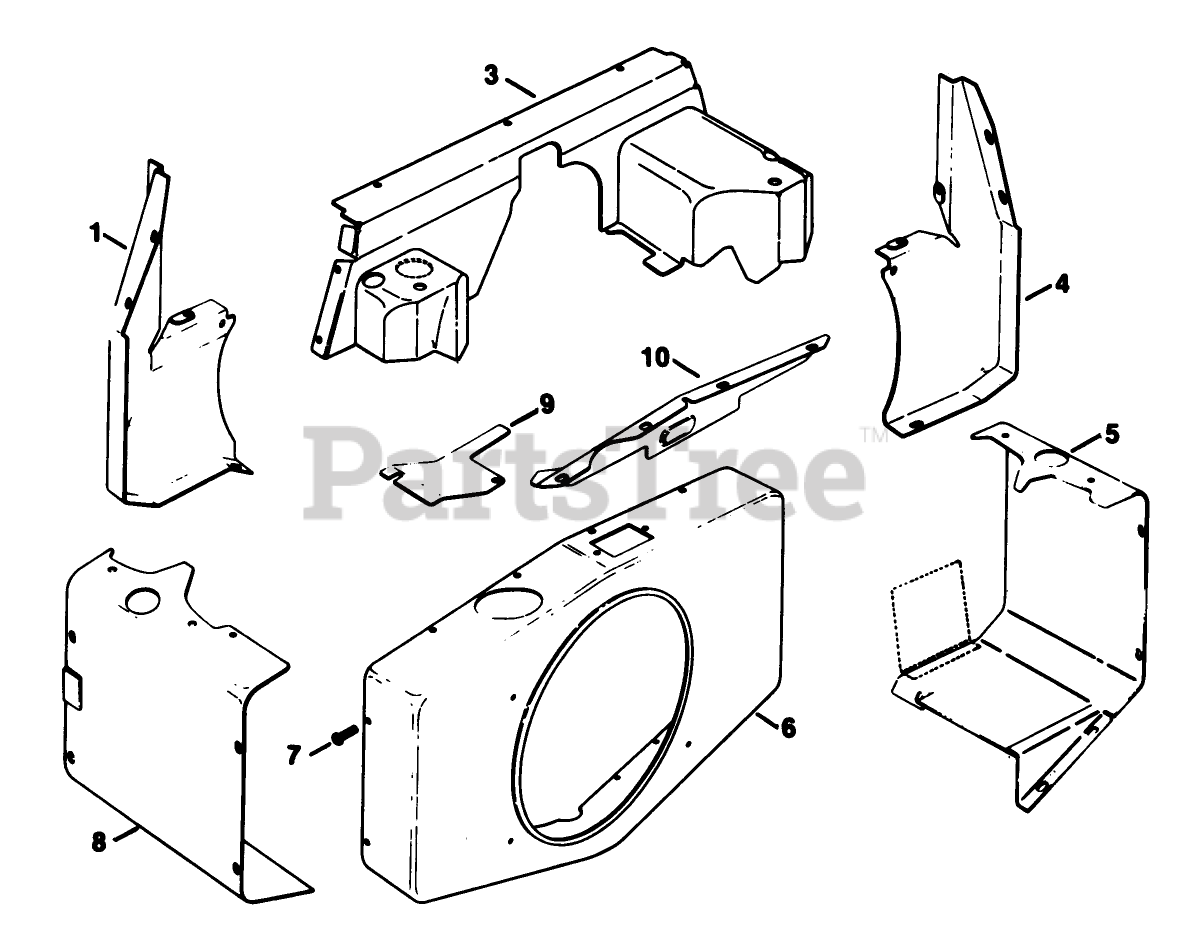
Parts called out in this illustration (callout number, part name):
1	Duct-#2 Side Air
3	Cover-Air Duct
4	#1 Side-Air Duct
5	Baffle-#1 Cylinder Head
6	Housing Blower
7	Screw
8	Baffle-#2 Cylinder Head w/Rear Cylinder Baffle
9	Baffle-Cylinder Head
10	Support-Upper Housing
